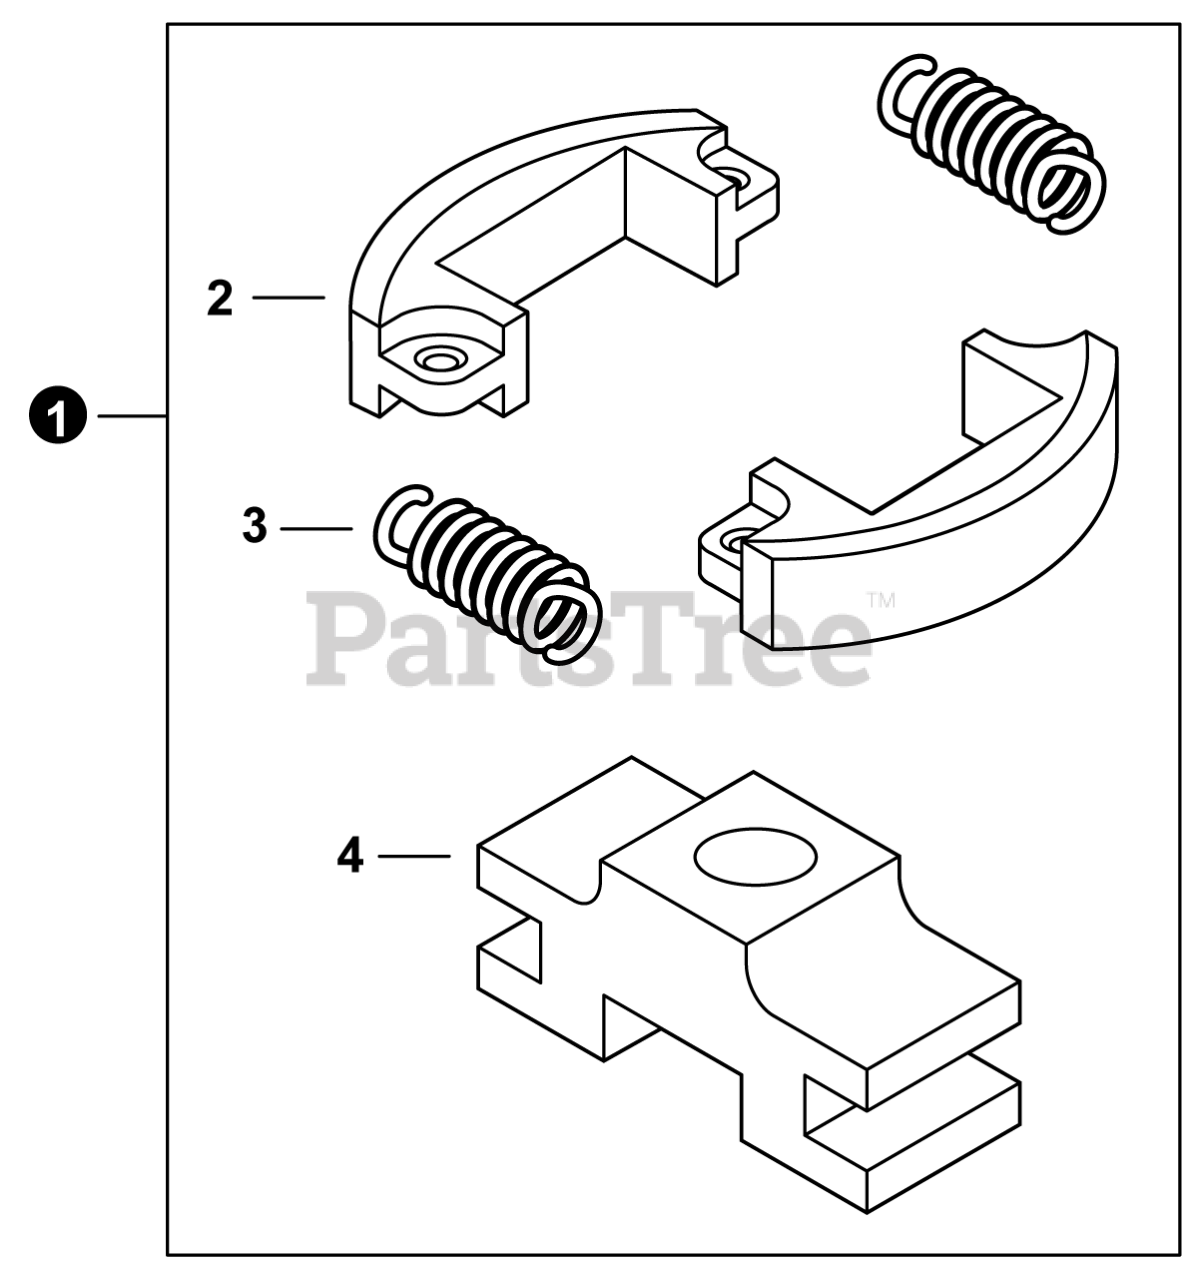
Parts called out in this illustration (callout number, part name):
1	CLUTCH ASSY
2	SHOE, CLUTCH
3	SPRING, CLUTCH
4	HUB, CLUTCH
